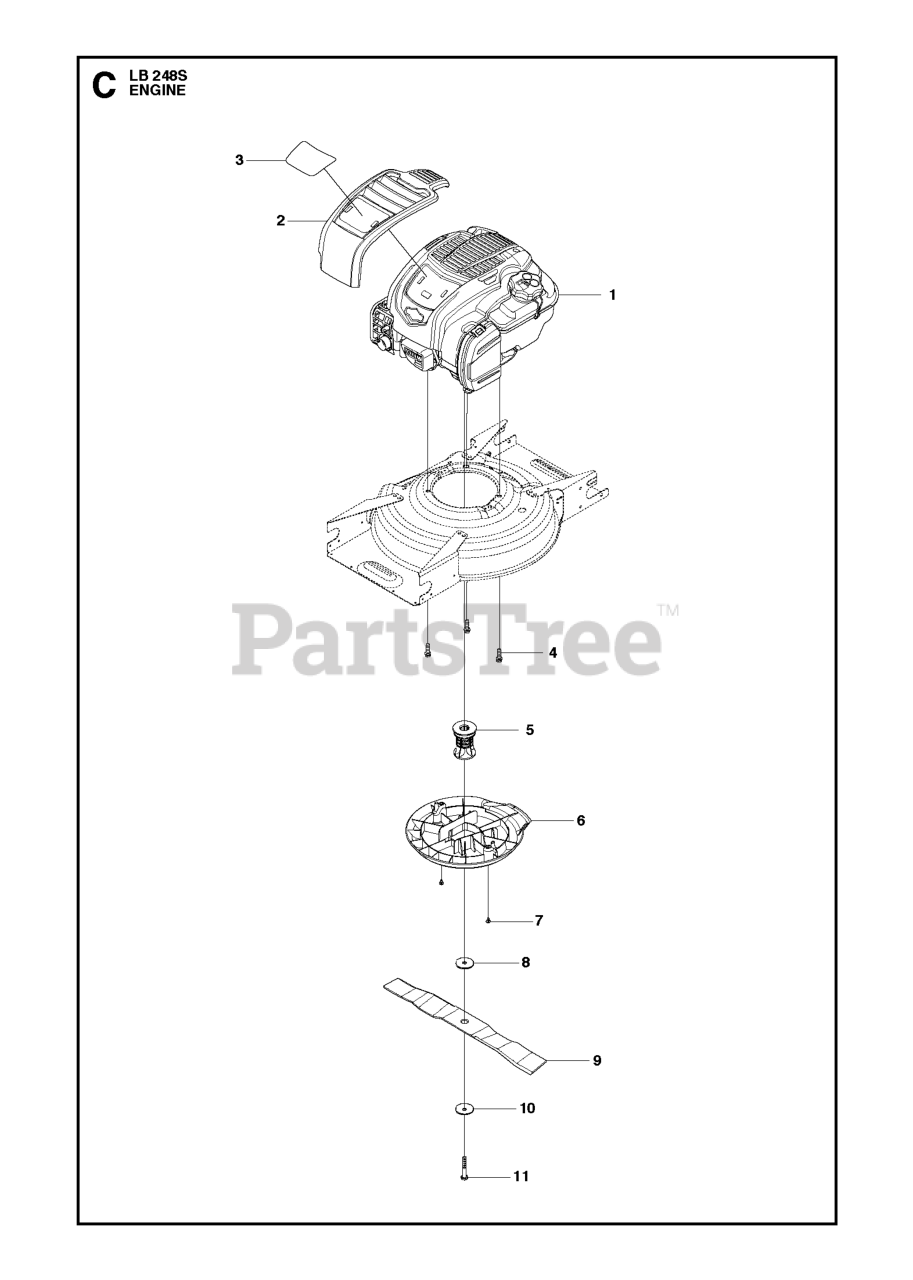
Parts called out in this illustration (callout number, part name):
4	BOLT 3/8-16X1-1/8
6	BELT COVER A009-2
7	SCREW ITXPANTT M5X10 ZPB (A00
